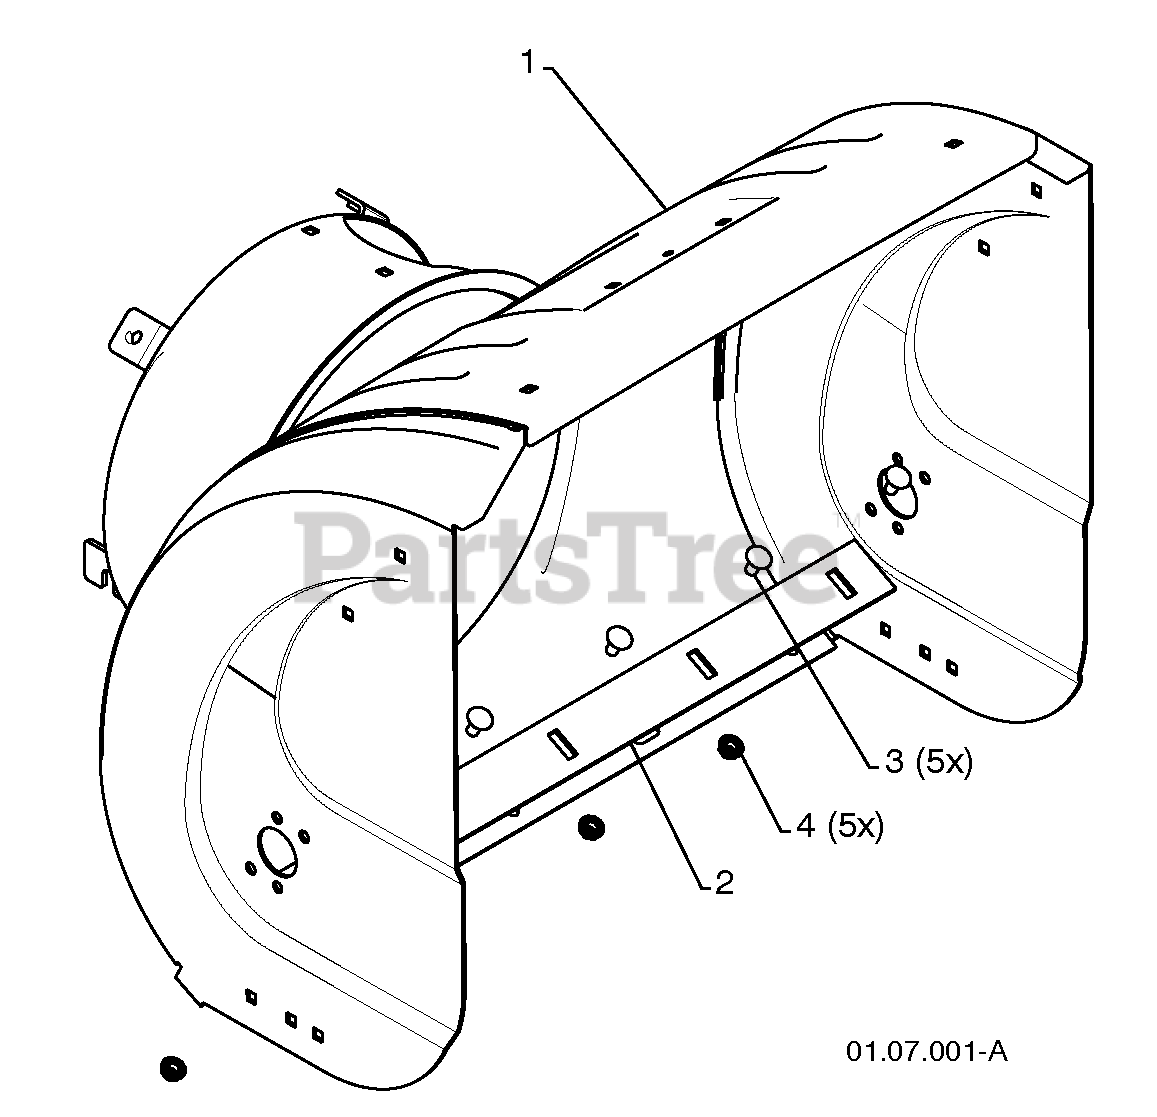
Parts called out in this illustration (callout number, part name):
1	AUGER HOUSING
2	SCRAPER BAR
3	CARRIAGE BOLT 5/16-18 X .625
4	NUT 5/16-18
